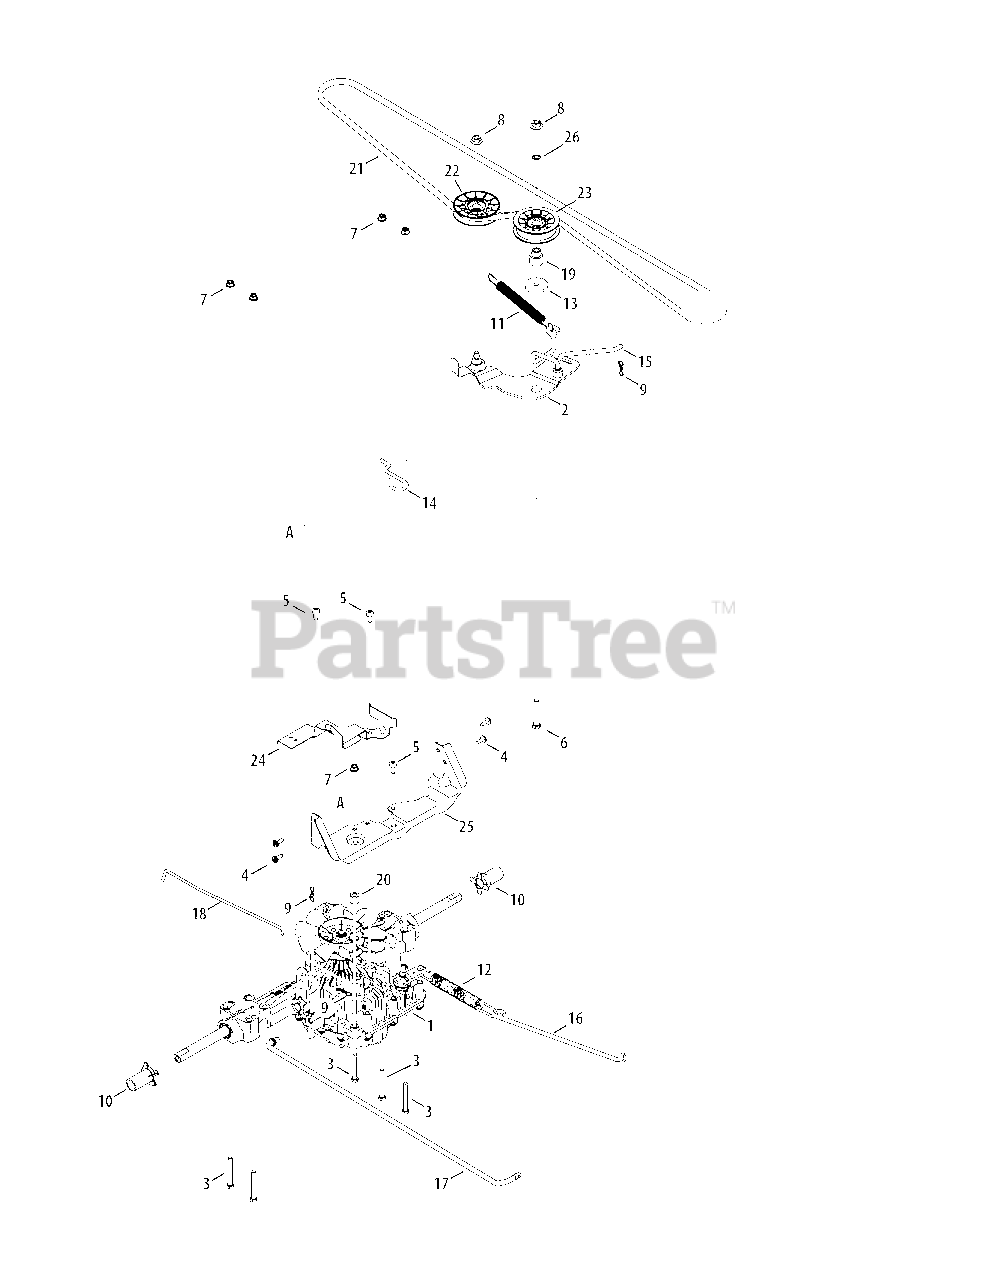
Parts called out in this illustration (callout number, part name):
1	Transmission, Tuff Torq K46
2	Idler bracket Assembly
3	Hex Screw, 5/16-18, 2.50, Gr5, Std
4	Screw, M6-1 x .625
5	Screw, Self-tapping, 5/16-18, 0.750
6	Hex Screw, 3/8-16, 2.25, Gr5
7	Nut, Flange Lock, 5/16-18, Nylon
8	Flange Lock Nut, 3/8-16
9	Pin, Cotter, Bow-Tie 72
10	Sleeve, .765 Id x 2.11
11	Spring, Extension, .790 Dia x 8.41
12	Spring, Extension, .90 Dia x 8.14
13	Shoulder Spacer, .884 x .190
14	Deck Spring Rod
15	Idler Link
16	Rod, Brake, Tuff Torq
17	Rod, Control, Tuff Torq
18	Rod, Transmission, Bypass
19	Shoulder Spacer
20	Spacer, .34 x .75 x .63
21	Belt, V-Type
22	Idler Pulley, 3.56 OD
23	Idler Pulley, 3.00 OD
24	Belt Keeper Bracket
25	Transmission Bracket
26	Speed Nut
